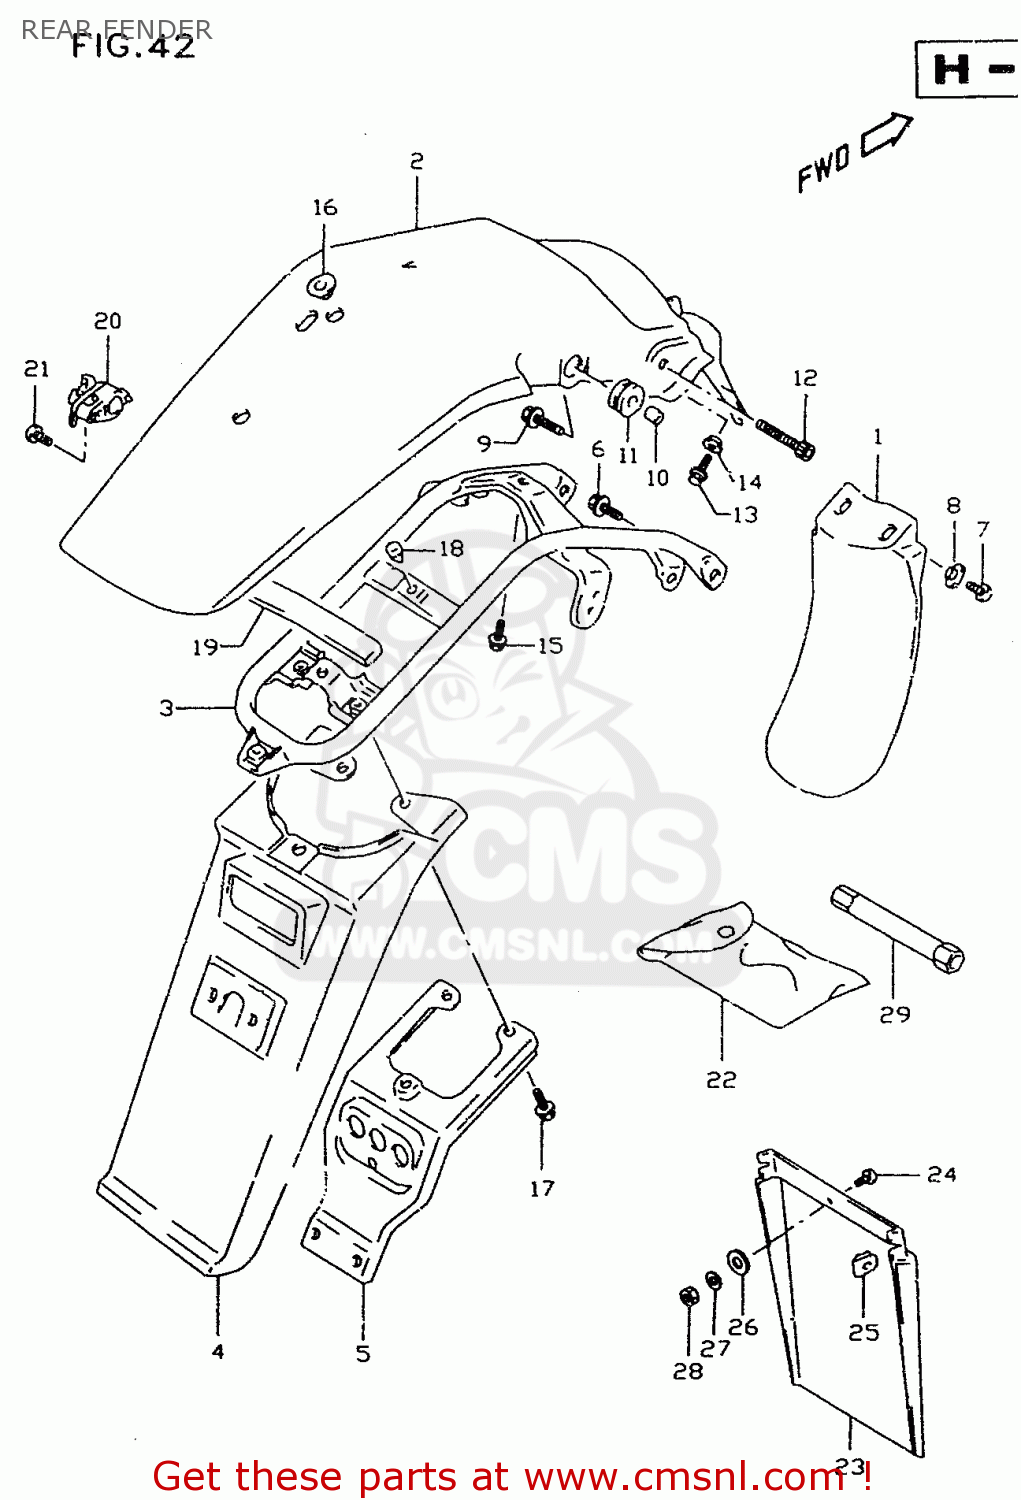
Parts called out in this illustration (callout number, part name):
1	BODY,RR FENDER FR
2	BODY,RR FENDER RR
3	REINF,RR FENDER
4	EXTENSION,RR FENDER
5	REINFORCEMENT,RR FENDER EXT
6	BOLT
7	SCREW 6X12
8	WASHER
9	BOLT(8X30)
10	SPACER(8.5X12X7)
11	CUSHION
12	BOLT(8X30)
13	BOLT
14	WASHER
15	BOLT
16	WASHER(14.5X26X1.6)
17	BOLT
18	CUSHION
19	CUSHION(25X185X15)
20	LOCK SET,HELMET
21	SCREW
22	TOOL ASSY
23	MUDGUARD,RR FENDER RR
24	SCREW 5X12
25	NUT
26	WASHER(5.5X16X1.2)
27	LOCK,WASHER
28	NUT
29	SPARK PLUG WRENCH(16)
